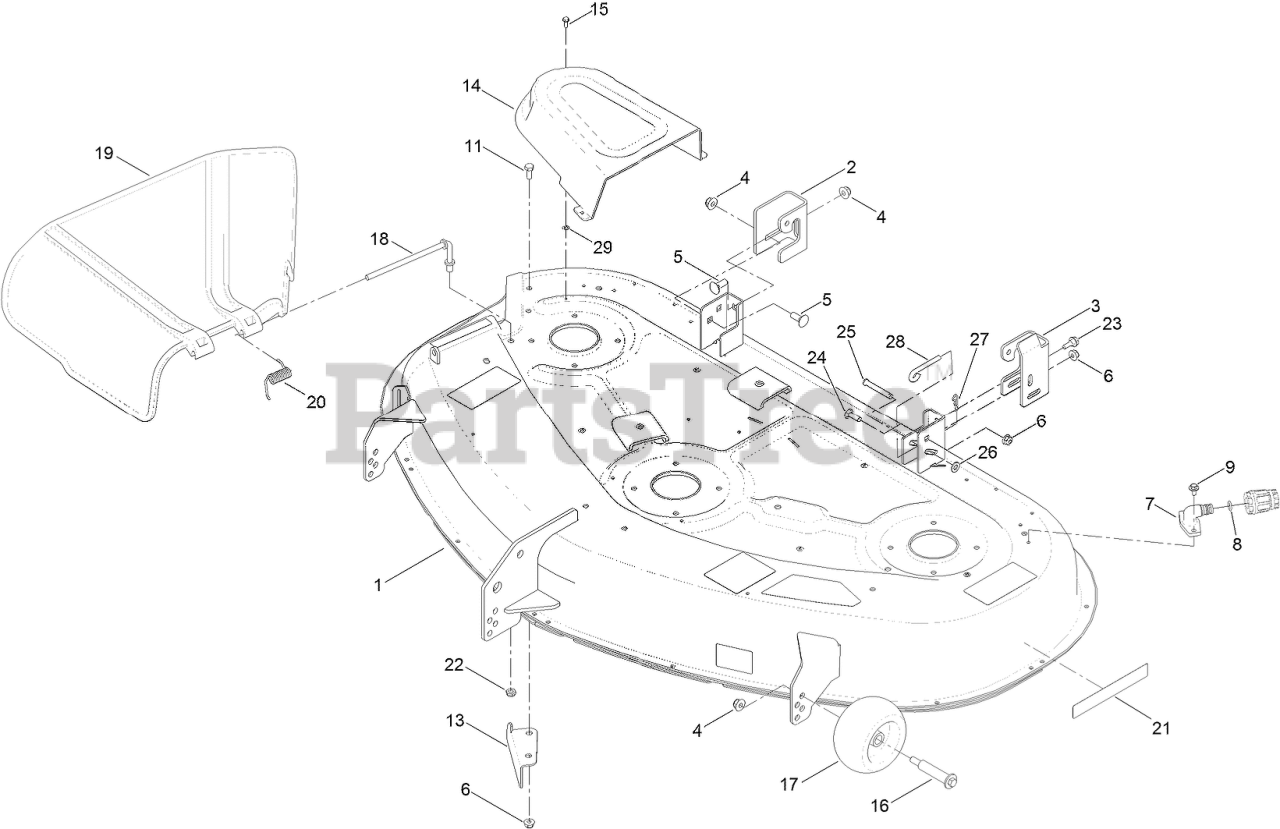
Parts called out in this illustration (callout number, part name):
1	50 INCH DECK AND DECAL ASM
2	BRACKET-HANGER, RH
3	BRACKET-HANGER, LH
4	NUT-HF, NI
5	BOLT-CARR
6	NUT-HF, NI
7	FITTING-WASHOUT
8	O-RING
9	SCREW-HHFTF
11	SCREW-HH
13	BAFFLE-CUTOFF
14	COVER-BELT
15	SCREW-TAPTITE
16	BOLT-SHOULDER
17	ROLLER-SCALP, ANTI
18	ROD-PIVOT
19	DEFLECTOR
20	SPRING-TORSION
21	DECAL-RECYCLER
22	NUT-LOCK, NI
23	SCREW-SHOULDER, HHF
24	SCREW-CARR
25	PIN-CLEVIS
26	WASHER-PLAIN
27	PIN-COTTER
28	ROD-LEVEL, DECK
29	NUT-RETAINING
